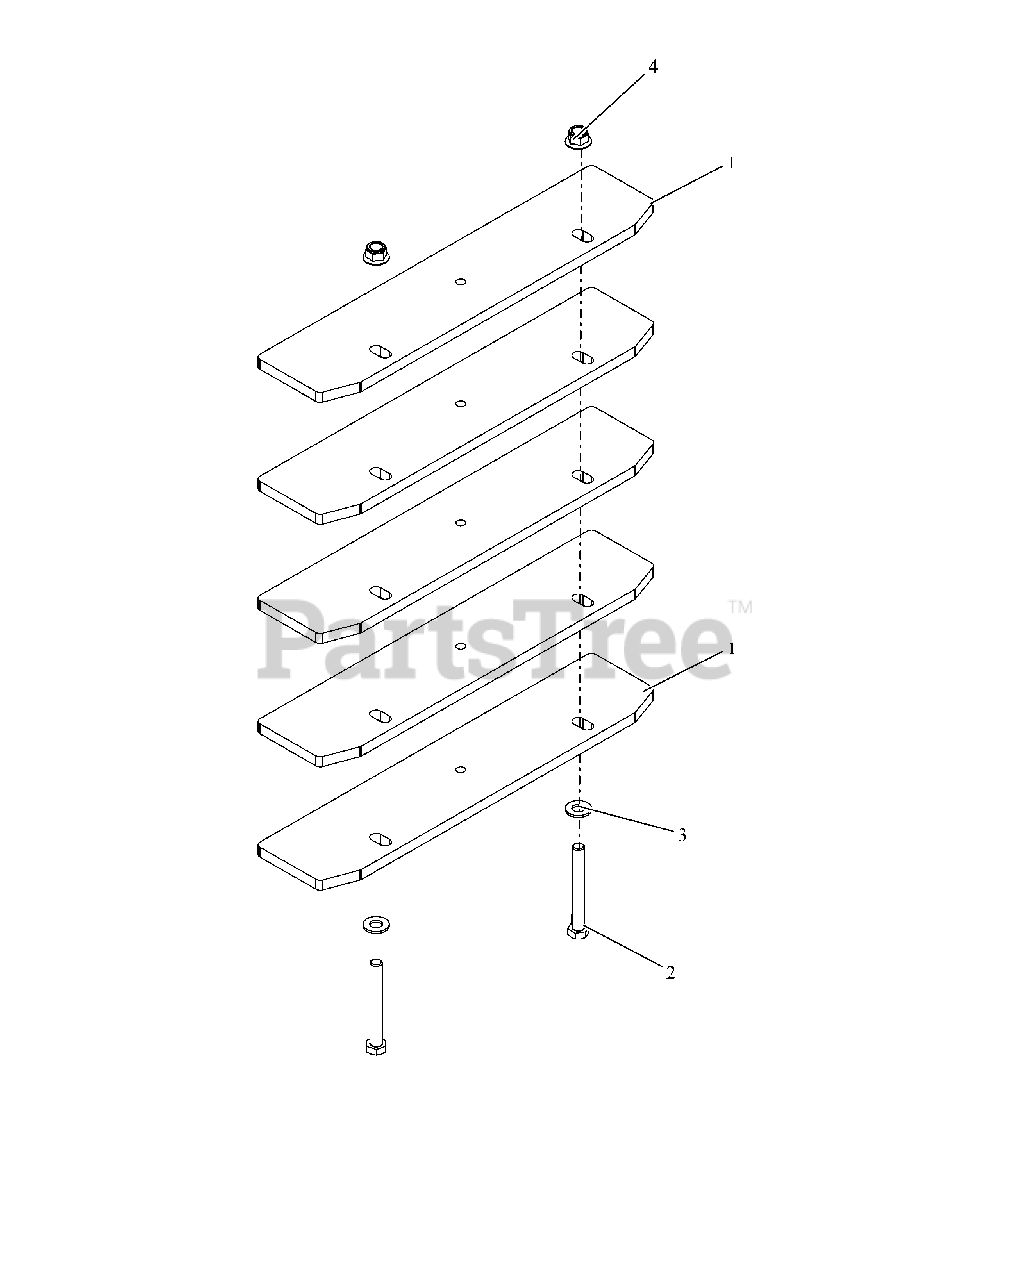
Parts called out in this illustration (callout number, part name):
1	PLATE, COUNTER WEIGHT
2	@BLT-HEX .50-13X4.00 GR5 YWZC
3	@WSHR-FL-STL.531X1.06X.095YWZC
4	@NUT-LK-NYL-FLG .50-13 YWZC
